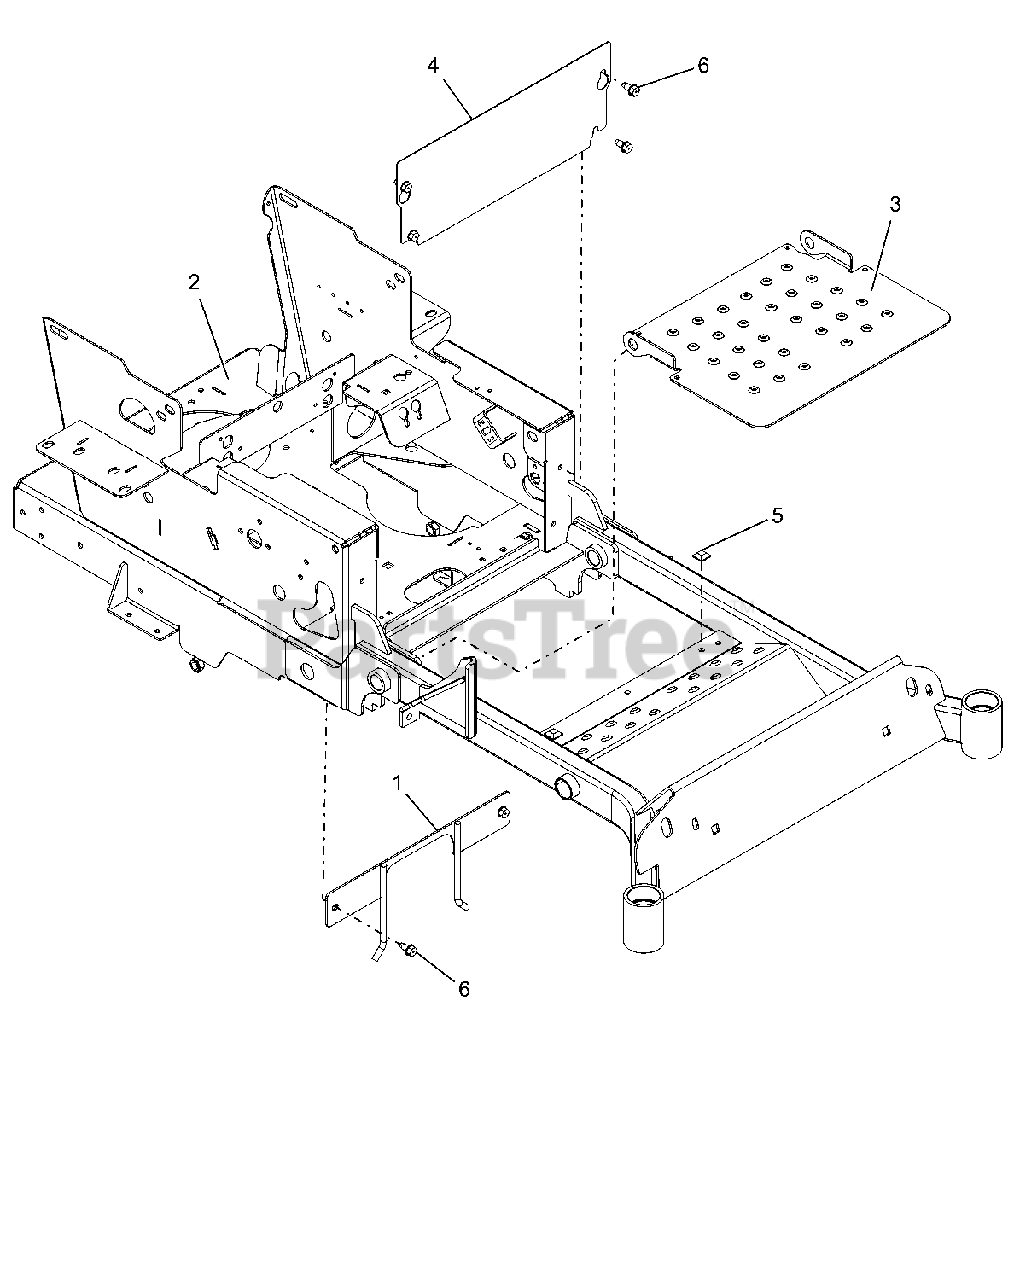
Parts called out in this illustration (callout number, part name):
1	WLDMT, PTO BELT FINGER-BLACK
2	WLDMT, 44"-48" HD FRAME (BLACK)
3	PANEL, INSPECTION
4	PLATE, KICK (RED)
6	SCR-TAP .38-16X.75 HWH TR YWZ
